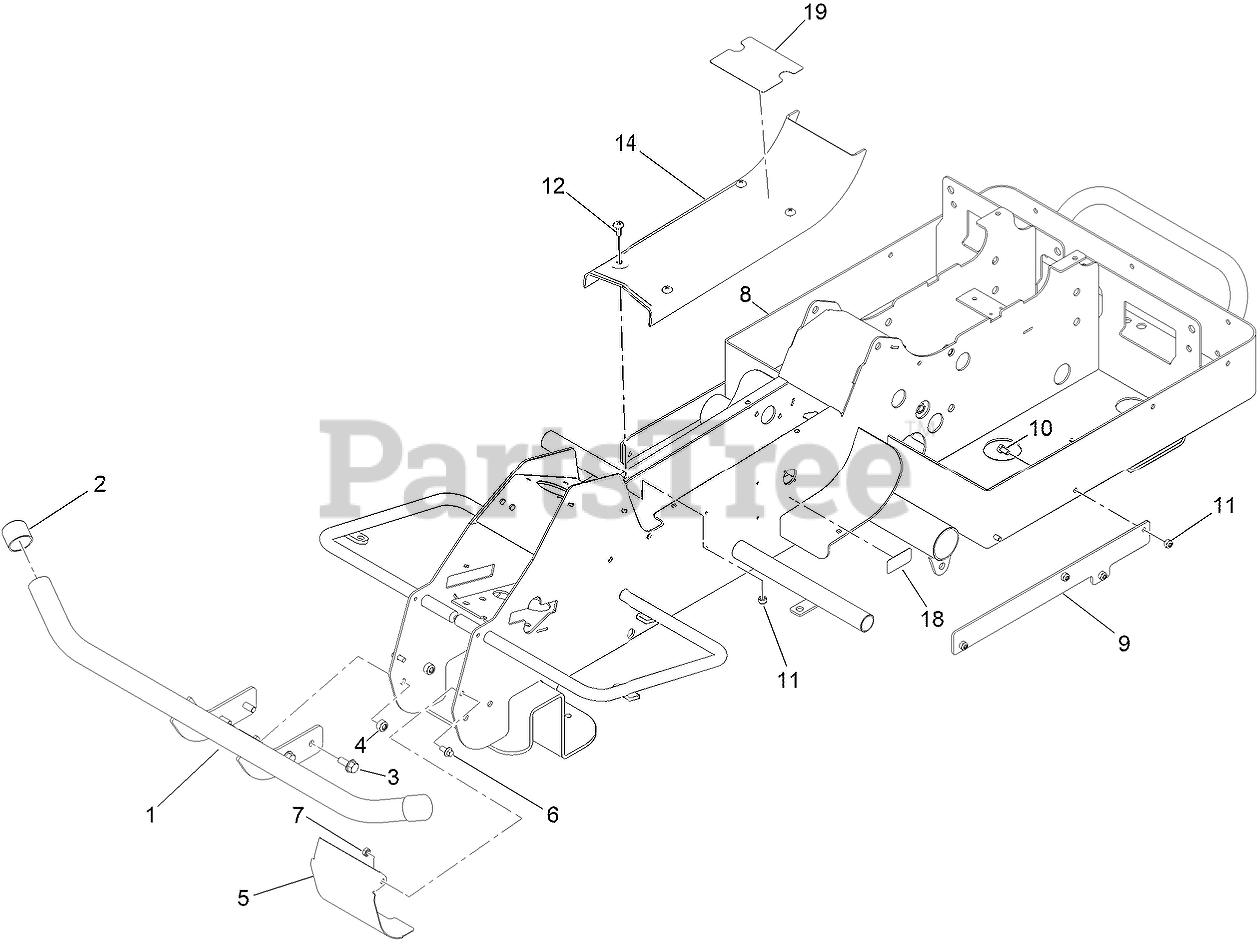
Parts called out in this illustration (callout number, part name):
1	BUMPER BAR, ASM
2	CAP, BUMPER BAR
3	SCREW-HHF
4	NUT-HEX, NI
5	FRONT PLATE, MAIN CHASSIS
6	BOLT, FLANGE
8	CHASSIS ASM
9	MOUNTS, SIDE PANNEL
10	SCREW-HH
11	NUT-NYLOC
14	TOP COVER, CHASSIS
18	DECAL - CHARGING PORT
19	DECAL - DANGER
